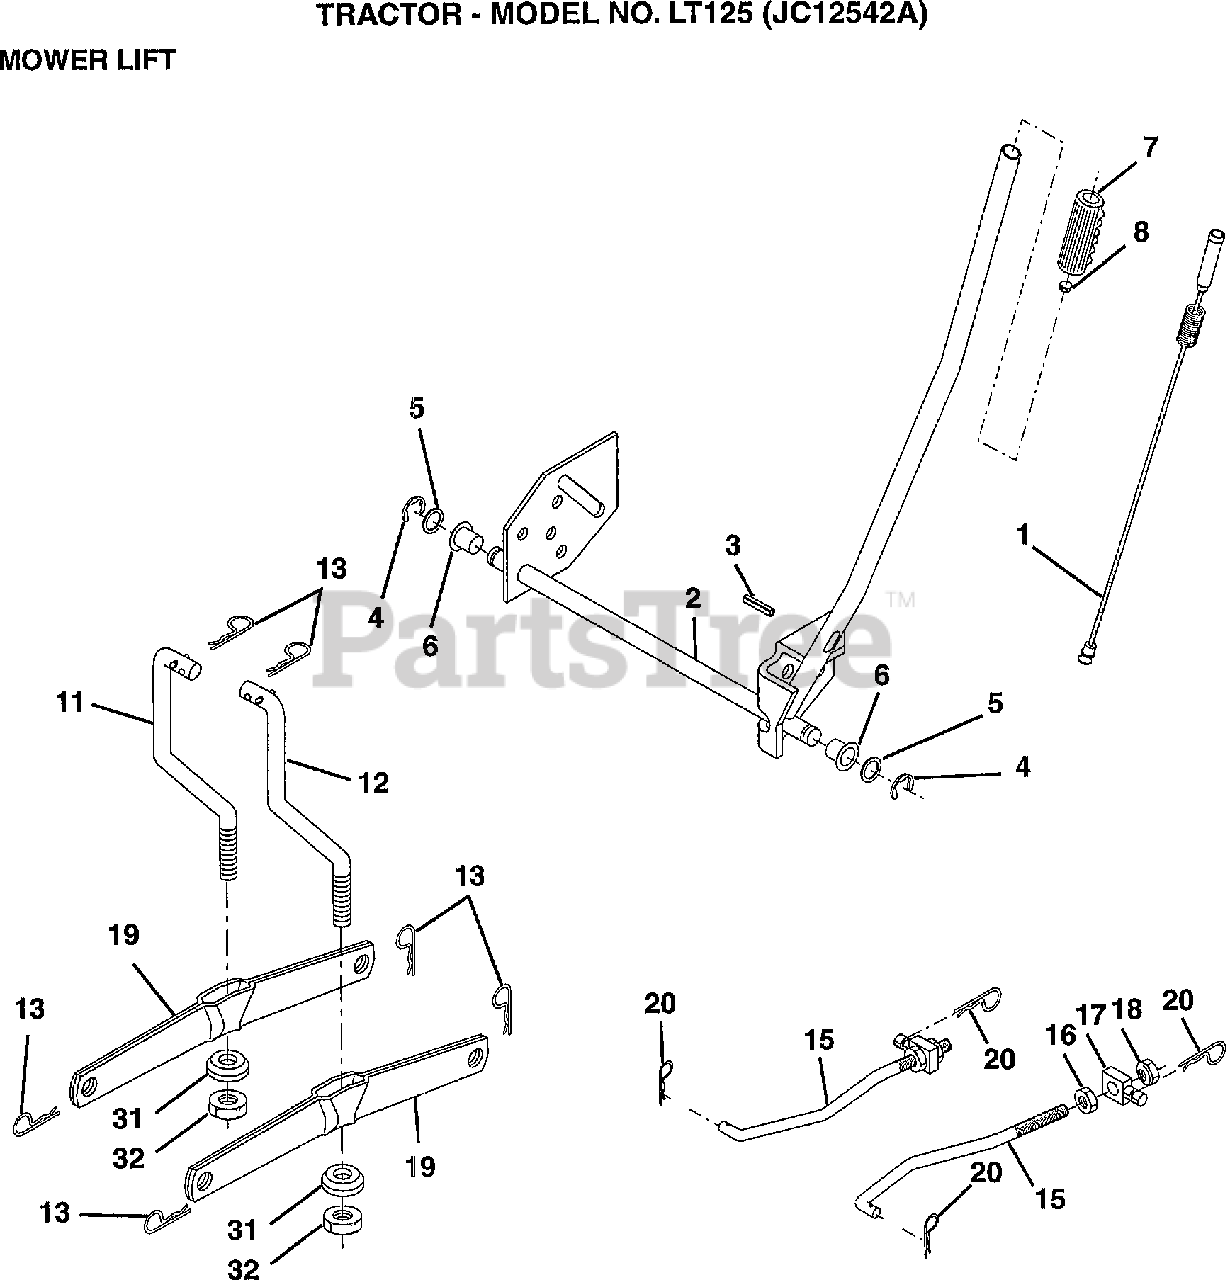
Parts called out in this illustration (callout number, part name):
4	E RING #5133-62
5	WASHER PLTD 21/32 X 1 X 21 GA
16	NUT JAM HEX 1/2-13
18	NUT LOCK W/WSH 1/2-13
32	NUT CROWNLOCK 3/8-24
